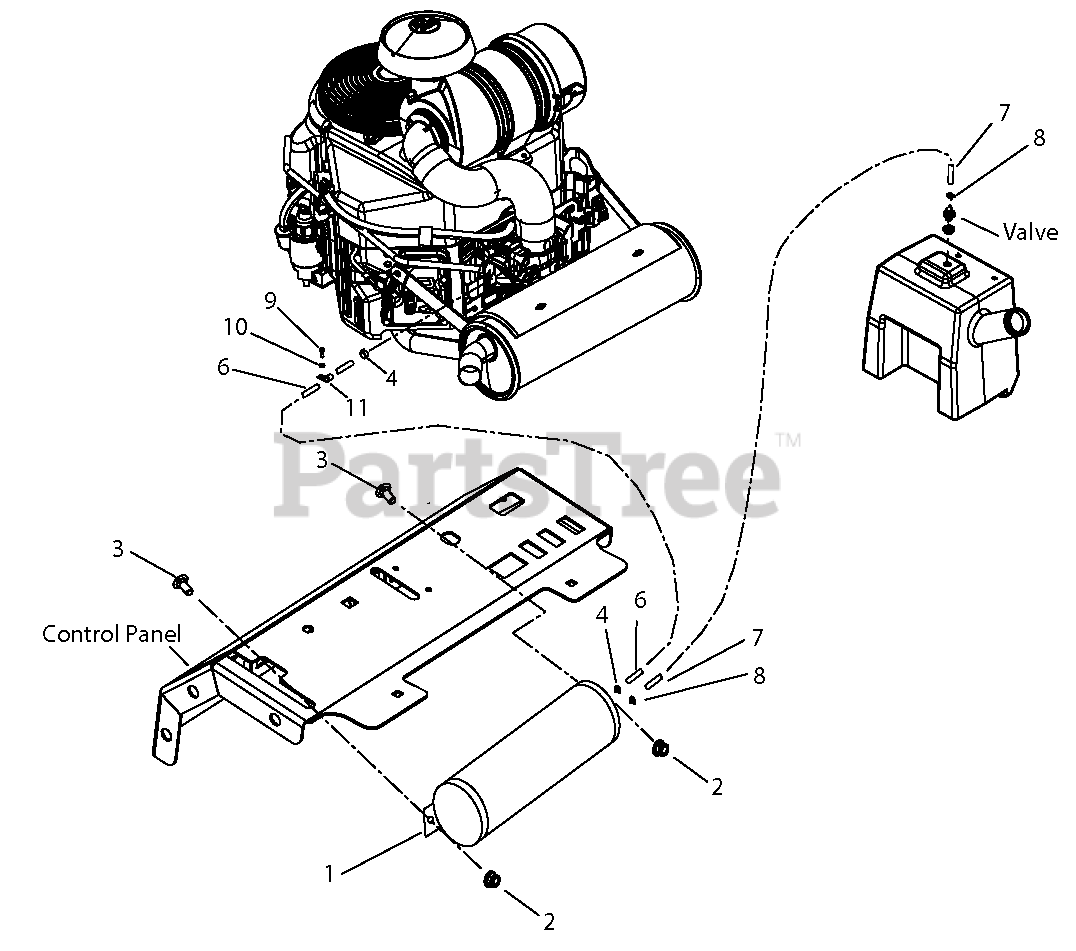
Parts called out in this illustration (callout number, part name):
1	CANISTER, CARBON 9.36 CAP
2	NUT-LK-NYL-FLG .38-16 YWZX
3	BLT-RDHDSQNK .38-16 X 1.00 GR5 YWZC
4	CLAMP, SPRING .188
5	CLAMP, SPRING .188
6	HOSE, FUEL 39"
7	HOSE, FUEL 17"
8	CLAMP, FUEL LINE .25
9	COLT, M8-1.25 X 20
10	WASHER-LK .31X.078 REGULAR
11	CLAMP, STEEL 1.0
